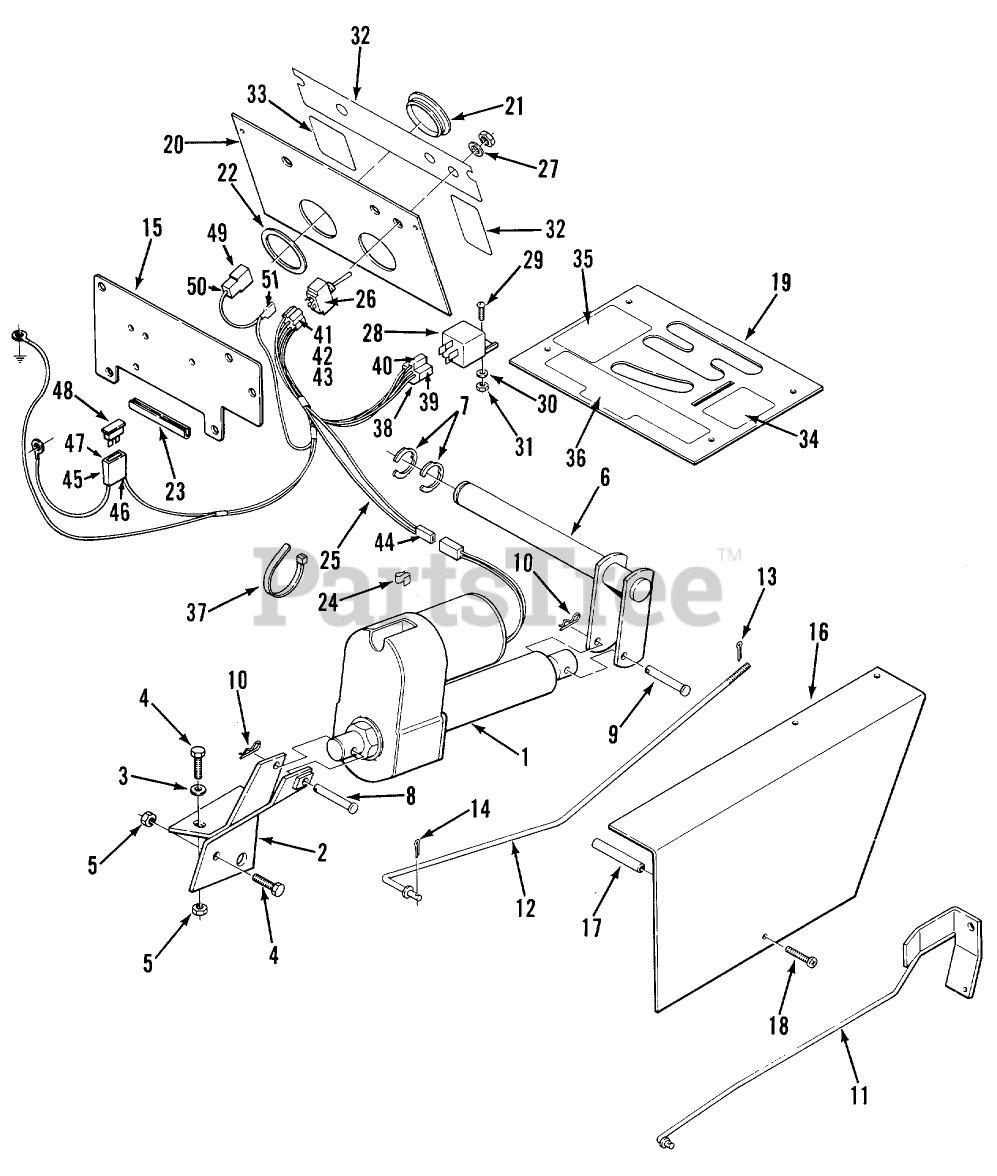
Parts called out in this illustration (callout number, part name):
1	Linear Actuator
2	ASSY LIFT BRACKET B
3	Washer
4	Bolt
5	NUT
6	ASSY LIFT ARM B
7	Retainer
8	Clevis Pin 1/2 x 2 3/4
9	CLEVIS PIN
10	Hairpin Cotter
11	ROD CLUTCH R
12	Brake Rod
13	Cotter Pin
14	Pop Rivet
15	X-REF 84225
16	COVER-L.H. R
17	Spacer
18	Pan Head Screw 1/4-20 x 1 3/4
19	PLATE SHIFT PATTE B
20	Hoodstand Plate
21	PLUG - HOLE
22	Backup Washer
23	EDGE TRIM 2" 102896
24	SPEED CLIP
25	Wiring Harness
26	SWITCH
27	Washer
28	RELAY
30	Washer
31	Nut
32	DECAL BACK PLATE
33	DECAL PTO
34	DECAL-PARKING, BRAKE
35	DECAL-SHIFT PATTERN
36	DECAL-DANGER
37	PLASTIC TIE
38	Connector Body (Part of Item 10)
39	Female Terminal (Part of Item 10)
40	TERMINAL FEMALE
41	CONNECTOR 5 WAY
42	Terminal
43	TERMINAL-TAB RCPT
44	CONNECTOR BODY B
45	AUTO-FUSEBLOCK TERM
48	FUSE-BLADE, 25 AMP
49	Wire Adapter
